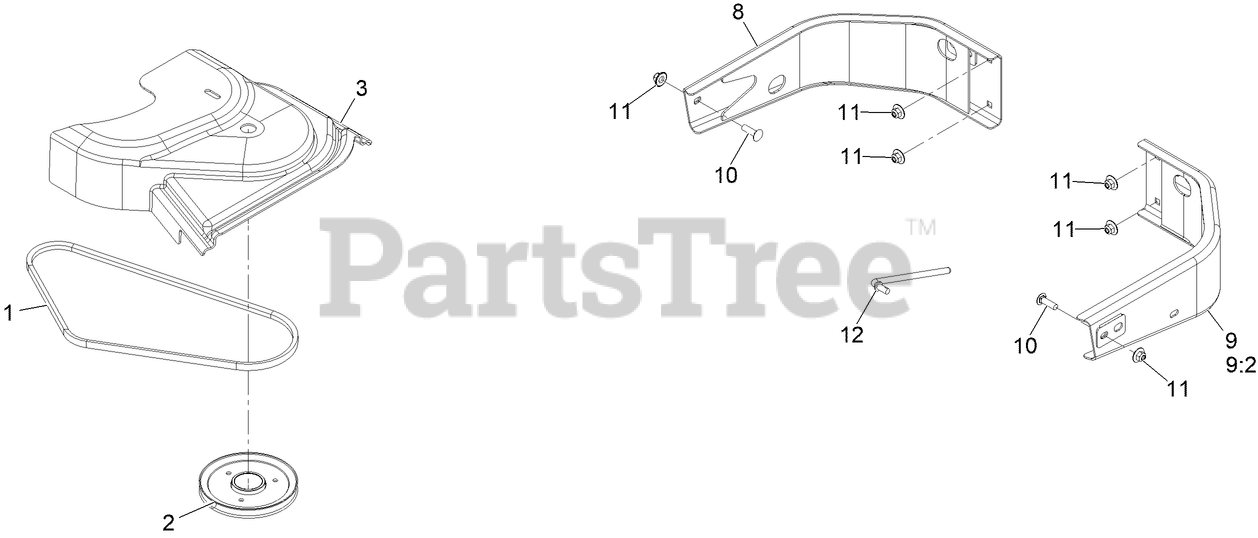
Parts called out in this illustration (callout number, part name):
2	SHEAVE,DRIVE LZUV 726
3	COVER,BELT UV 72
8	BUMPER-RH
9	LH BUMPER ASM
9:2	DECAL-WARNING
10	Bolt-Carriage 3/8-16 X 1 1/4
11	Nut-Nyloc 3/8-16 Flg
12	LINK-HANDLE
